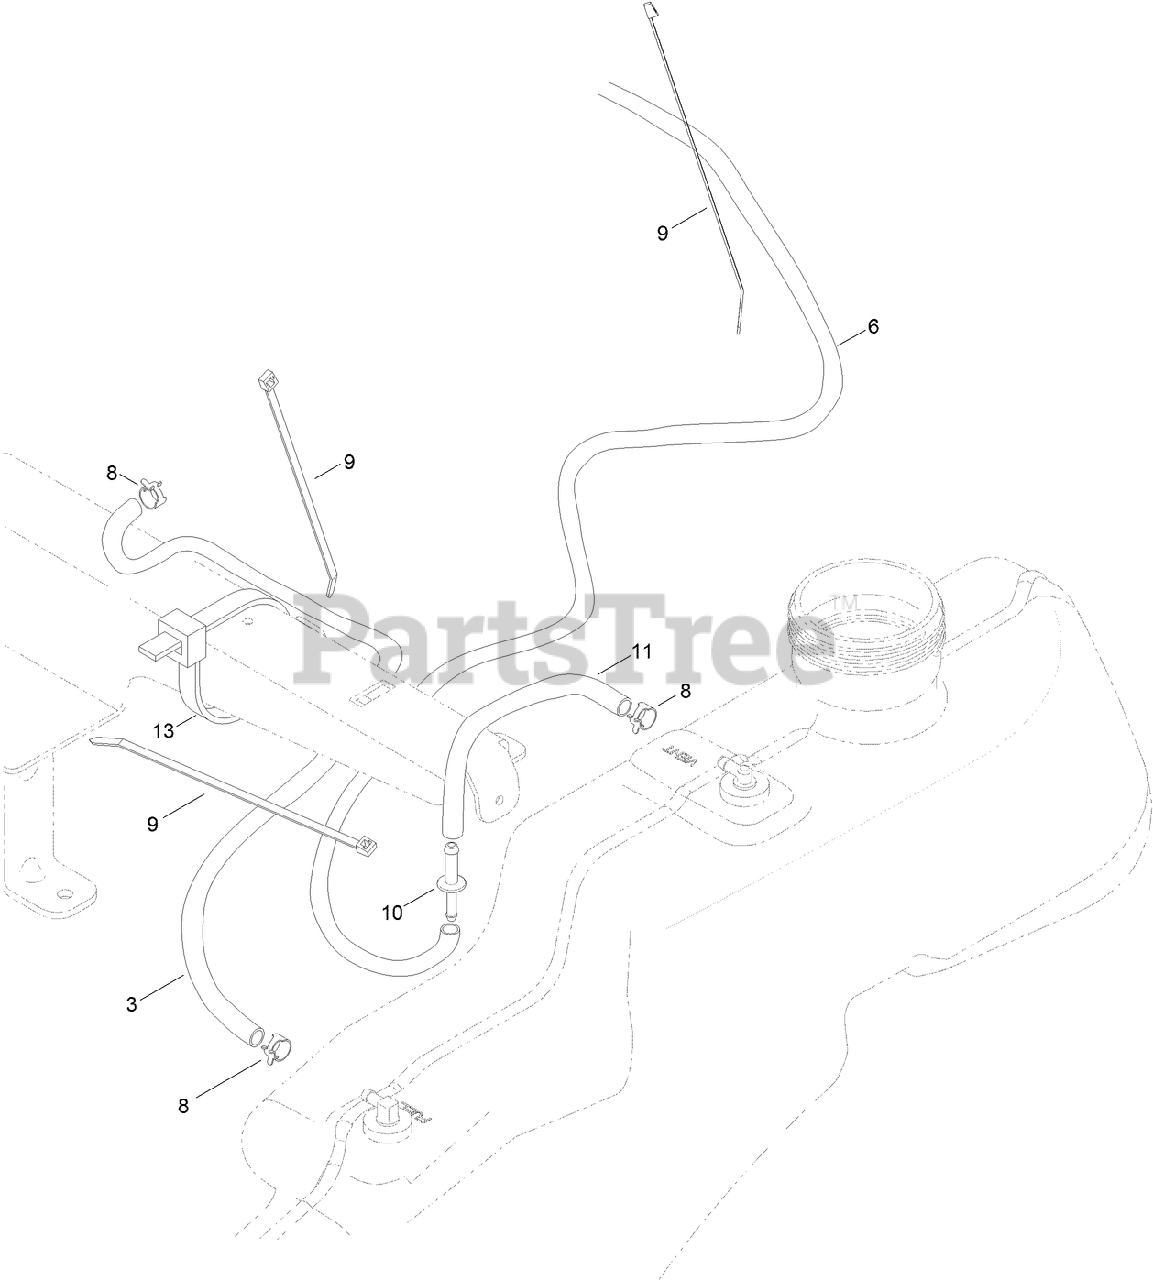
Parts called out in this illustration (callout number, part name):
3	HOSE-FUEL
6	HOSE-FUEL
8	CLAMP-HOSE
9	TIE-CABLE
10	ADAPTOR-ORIFICE
11	HOSE-FUEL
13	TIE-CABLE
